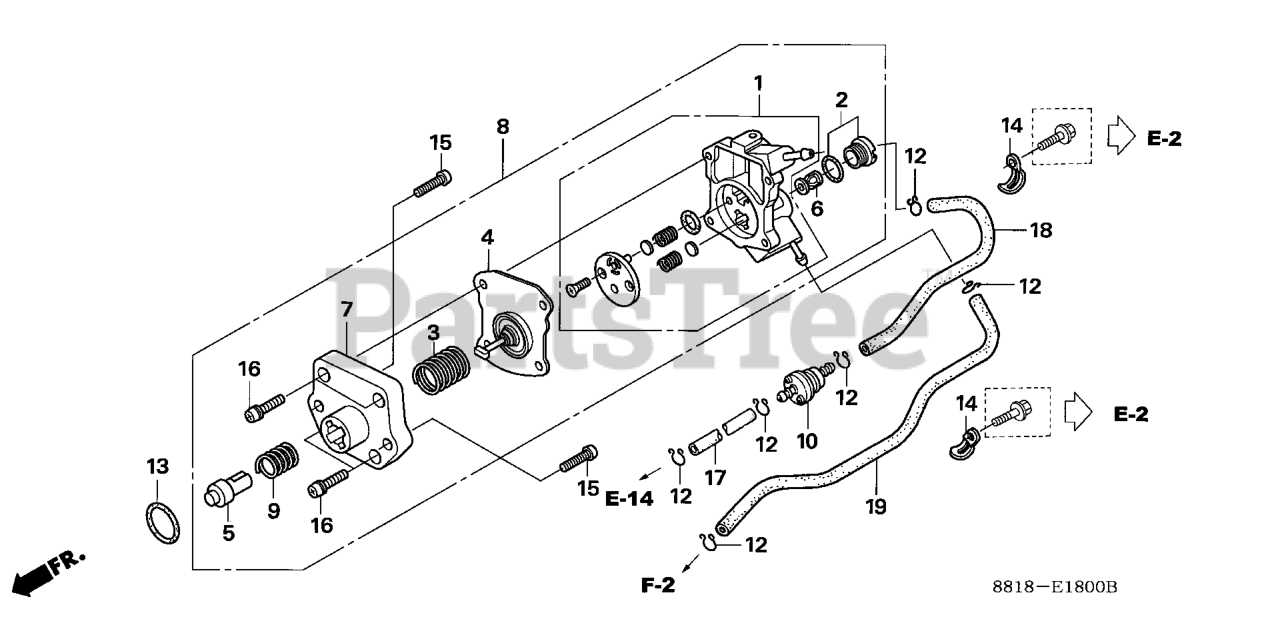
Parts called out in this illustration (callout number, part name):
1	BODY SET, PUMP
2	BOLT SET, HOLDING
3	SPRING, DIAPHRAGM
5	ROD, PUSH
6	SCREEN, FUEL STRAINER
7	BODY (LOWER)
8	PUMP ASSY., FUEL (MSDS)
9	SPRING, PUSH ROD
10	FILTER, FUEL
12	CLIP, TUBE (B8)
13	O-RING (20.8X2.4)
14	CLIP B, CORD
15	SCREW, PAN (6X20)
16	SCREW-WASHER (4X16)
17	BULK HOSE, FUEL (4.5X3000) (Honda Code 5137104). (4.5X140)
18	BULK HOSE, FUEL (4.5X3000) (Honda Code 5137104). (4.5X140)
19	BULK HOSE, FUEL (4.5X3000) (Honda Code 5137104). (4.5X140)
